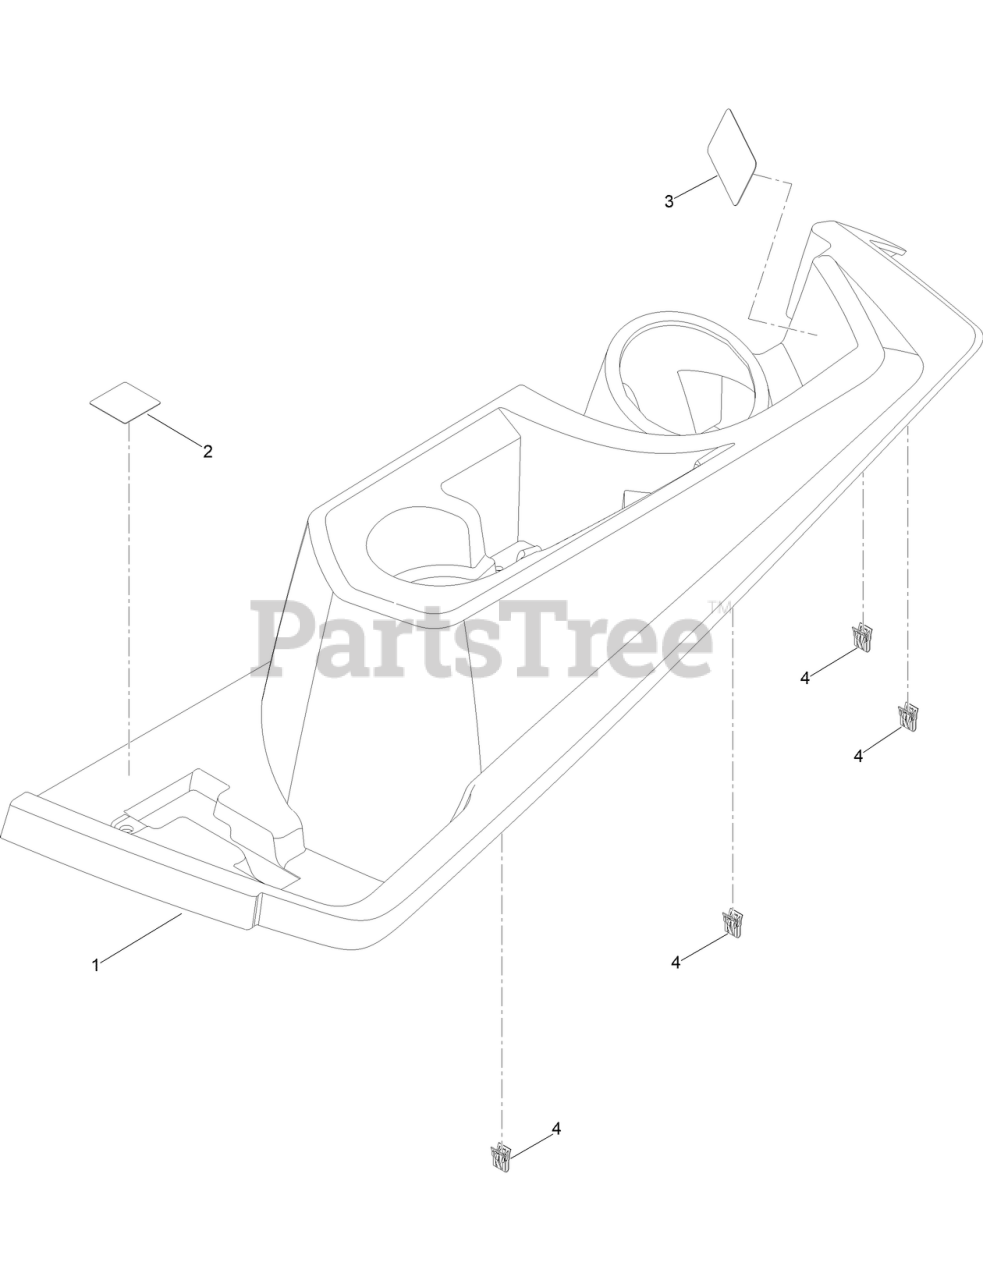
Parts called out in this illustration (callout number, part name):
1	POD-UPPER, LH
2	DECAL-CONTROL, LH
3	DECAL-FUEL FILL
